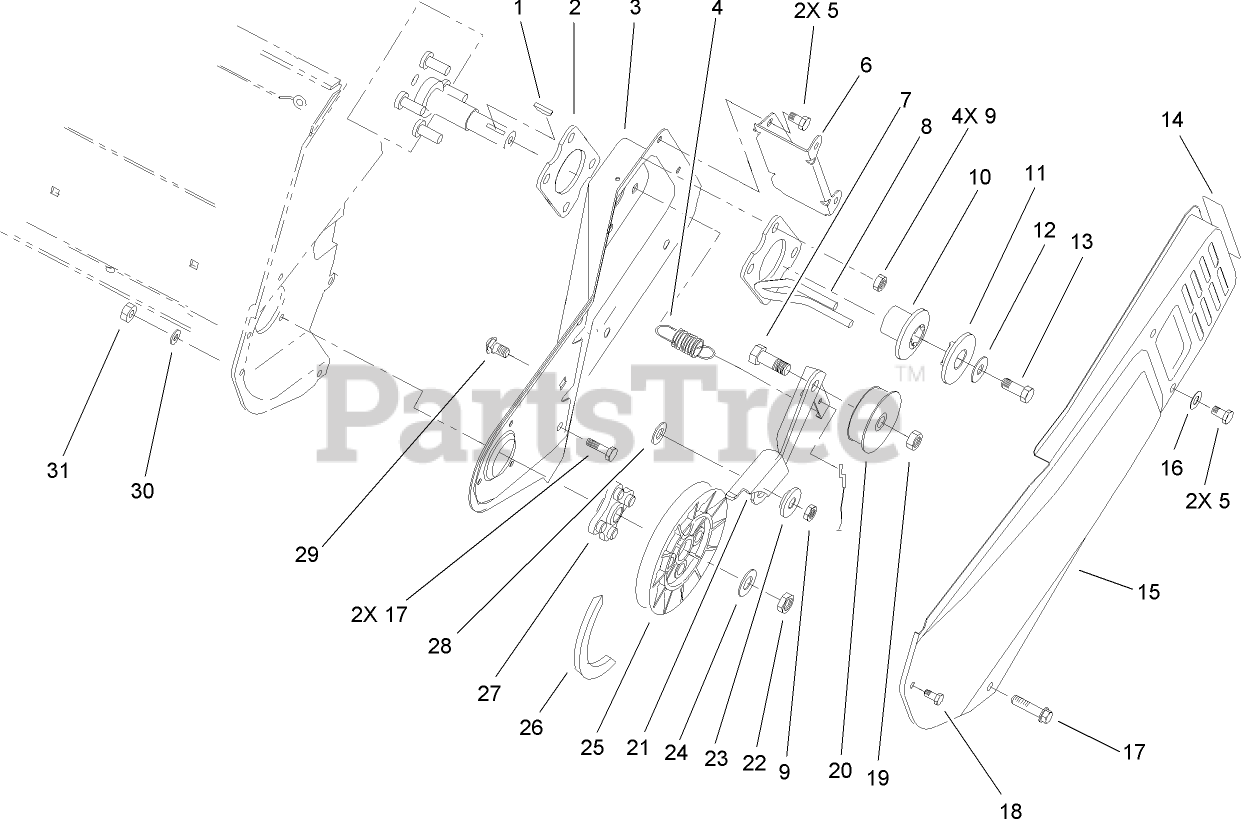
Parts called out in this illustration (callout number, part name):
1	KEY-WOODRUFF
2	PLATE-ENGINE
3	SIDEPLATE-LH
4	SPRING-BRAKE
5	SCREW-HWH
6	BRACKET-COVER, BELT
7	SCREW-HH
8	GUIDE-BELT
9	NUT-LOCK, NI
10	HUB-HALF SHEAVE
11	CAP-HALF SHEAVE
12	WASHER-FLAT
13	SCREW-HH
14	DECAL-HOT
15	COVER-BELT
16	WASHER-FLAT
17	SCREW-PLASTIC
20	PULLEY-IDLER
21	ARM-BRAKE
22	NUT-LOCK, NI
23	BUSHING-IDLER
24	WASHER-FLAT
25	PULLEY-DRIVEN
26	V BELT
28	WASHER
29	SCREW-CARR
30	WASHER-FLAT
31	NUT-LOCK, NI
